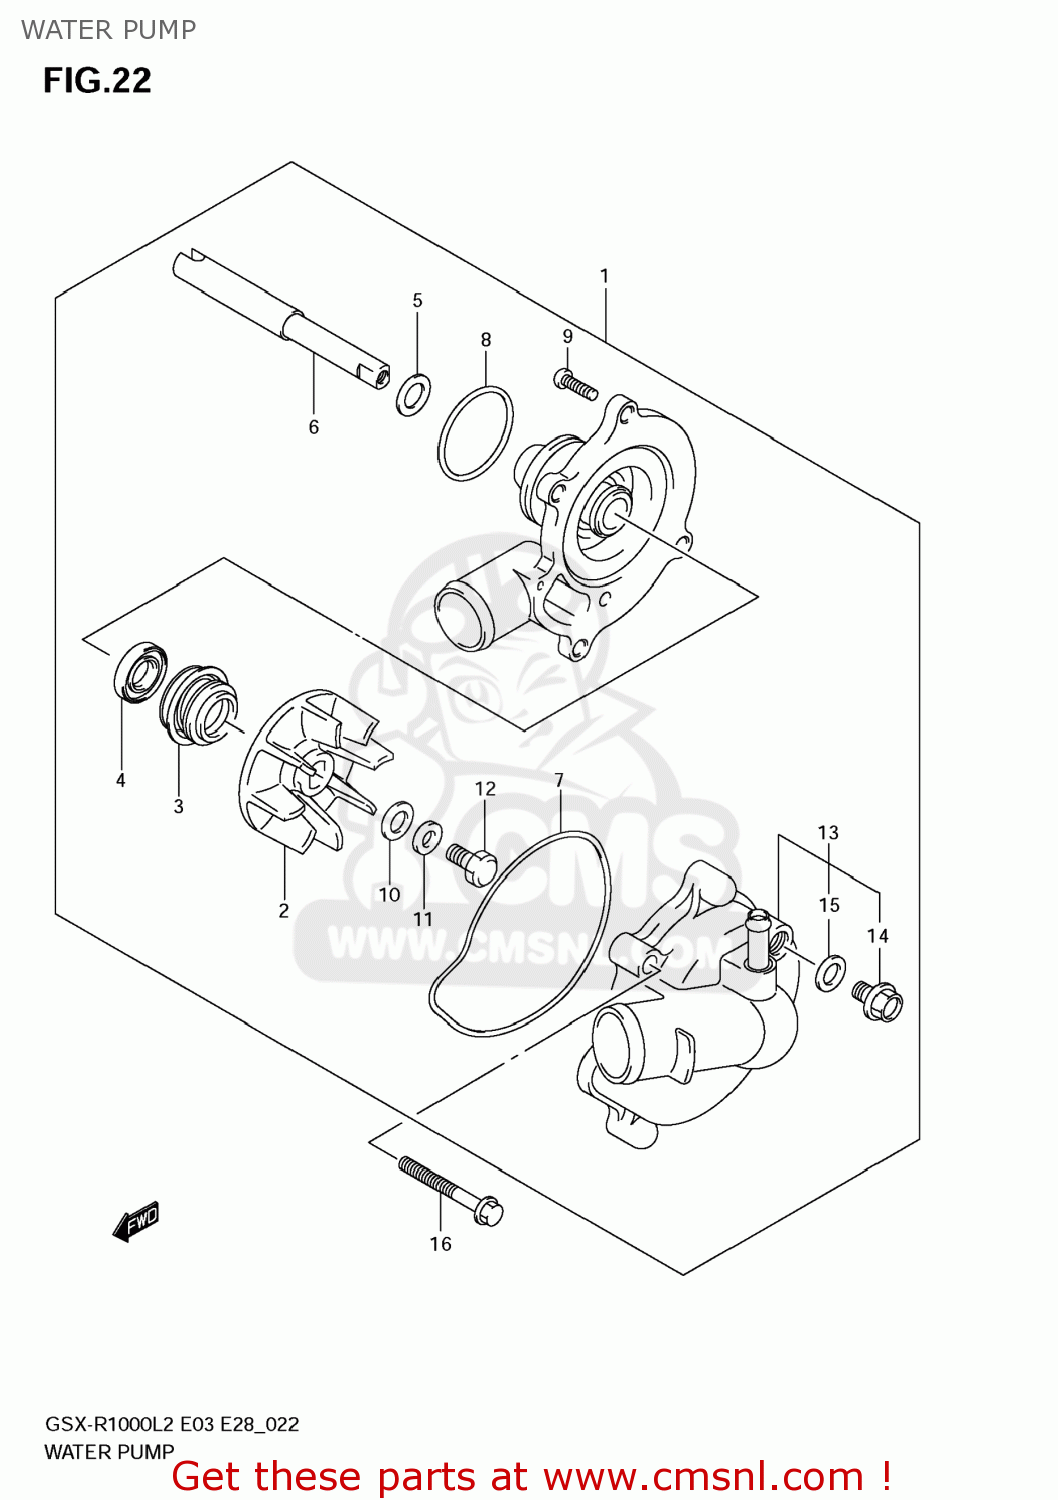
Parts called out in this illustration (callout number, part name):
1	PUMP ASSY,WATER
2	IMPELLER
3	SEAL,MECHANICAL
4	SEAL,OIL
5	WASHER
6	SHAFT
7	O RING
8	O RING,WATER PUMP HOLDER
9	SCREW
10	GASKET(6X15X2.2) (NAS)
11	WASHER
12	BOLT(6X13)
13	CASE,WATER PUMP
14	BOLT,DRAIN
15	GASKET(8.2X14X1) (NAS)
16	BOLT
